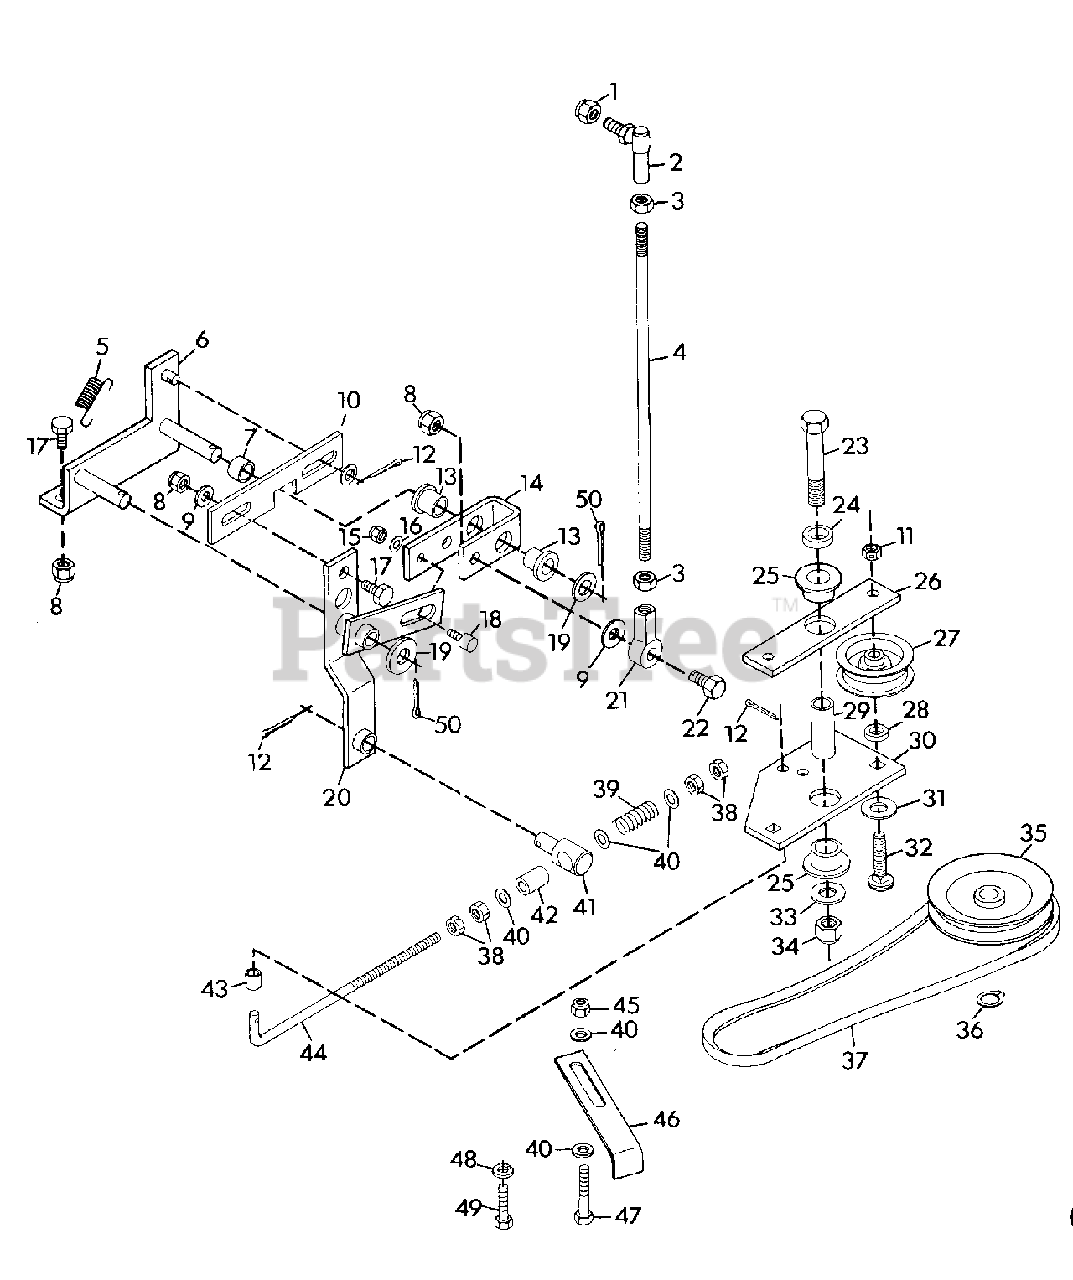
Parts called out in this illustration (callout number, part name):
1	NUT, LOCK 3/8-24
2	BALL JOINT, STEERING
3	NUT, HEX 3/8-24
4	ROD, CLUTCH ACTUATING
5	SPRING, NEUTRAL DETENT
6	WELDMENT, FWD-REV CONTROL BRACKET
7	BUSHING
8	NUT, LOCK 3/8-16
9	WASHER, FLAT .406X.812X.065
10	STRAP, CLUTCH
11	NUT, LOCK 3/8-16
12	PIN, COTTER .09X.75
13	BUSHING, .513X.750X.625
14	LEVER, FWD-REV ACTIVATING
15	NUT, LOCK 1/4-28
16	WASHER, FLAT .281X.625X.065
17	BOLT, HEX 3/8-16X1.00
18	ROLLER, CLUTCH CAM
19	WASHER, FLAT .531X1.062X.095
20	WELDMENT, FWD-REV CAM
21	ROD END, SPHERICAL BEARING
22	BOLT, HEX 3/8-16X1.25
23	BOLT, HEX 1/2-13X3.00
24	SPACER
25	BUSHING, NYLON .76X1X.6 FLANGE
26	PLATE, IDLER
27	SHEAVE, IDLER
28	SPACER, IDLER .406X.750X.188
29	SPACER
30	PLATE, IDLER
31	WASHER, FLAT .531X1.063X.095
32	BOLT, 3/8-16X1.75 RD HD SQ NK
33	WASHER, FLAT .531X1.250X.100
34	NUT, LOCK 1/2-13
35	SHEAVE, TRANSMISSION
36	RING, RETAINING
37	BELT, ENGINE-TRANSMISSION DRIVE
38	NUT, HEX 5/16-18
39	SPRING
40	WASHER, FLAT .344X.688X.065
41	PIVOT
42	BUSHING, NYLON .375X.503X.875
43	BUSHING, .375X.500X.437
44	ROD, CLUTCH
46	GUIDE, V-BELT
47	BOLT, HEX 5/16-18X1.75
48	WASHER, LOCK 8MM SPRING
49	BOLT, HEX M8 X 1.25 30MM
50	PIN, COTTER .125X1.00
